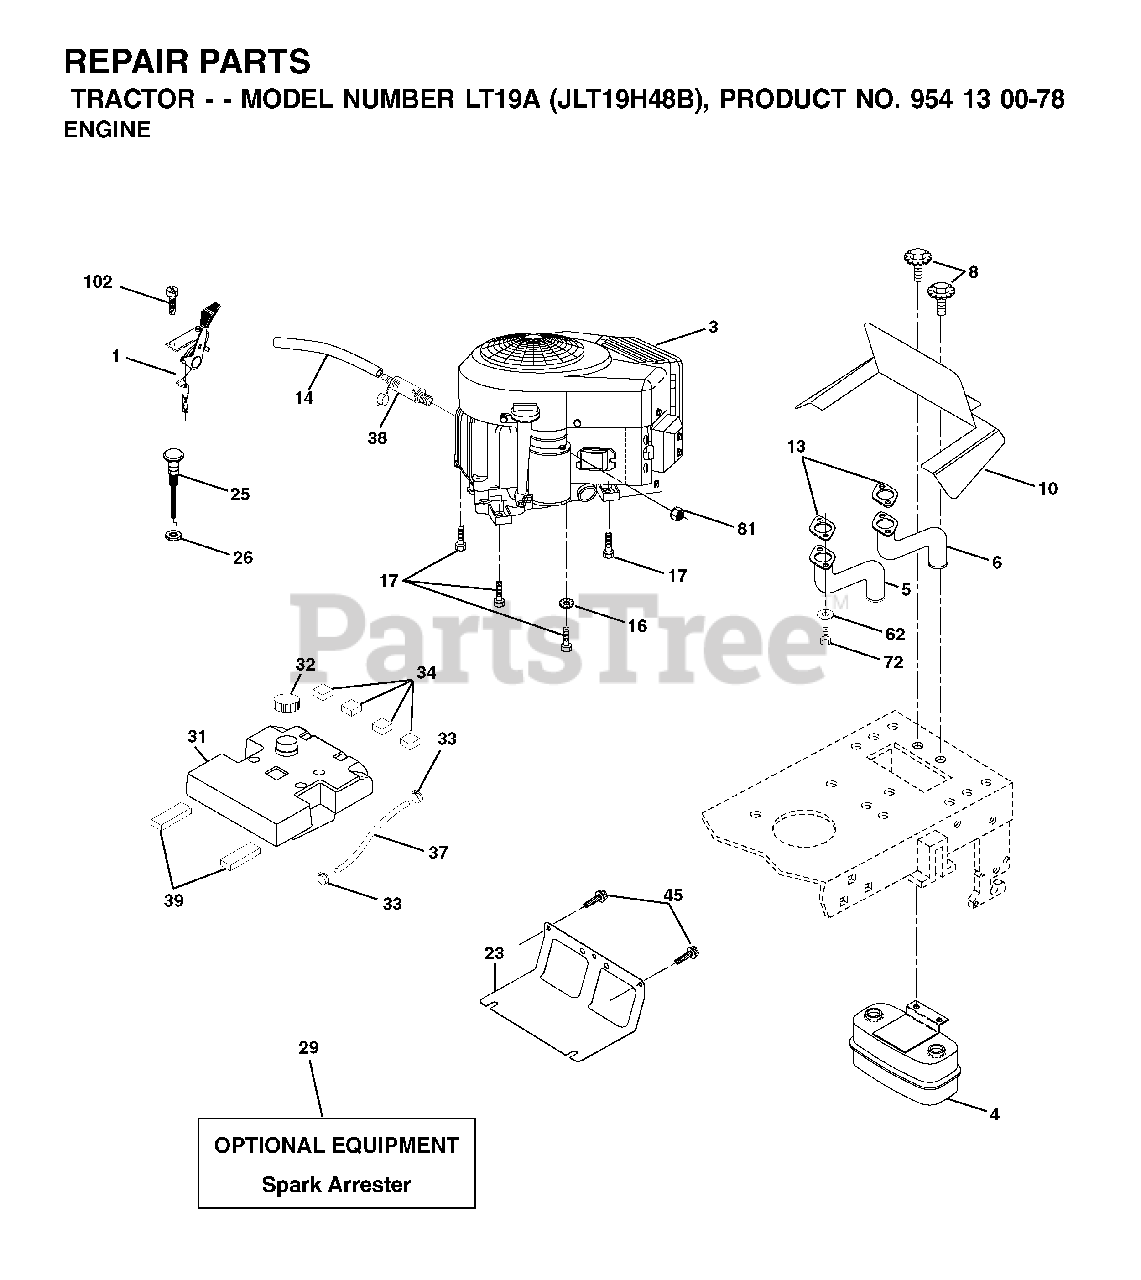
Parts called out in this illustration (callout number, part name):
1	THROTTLE CABLE
4	MUFFLER.TWIN.CYL.LOW.TONE
5	TUBE MANIFOLD LH
6	EXHAUST TUBE RH
8	BOLT, 5/16-18 X 1 3/4
10	SHIELD.BROWNING.B&S
13	GASKET.MUFFLER
14	TUBE, DRAIN OIL ASM.
16	LOCKWASHER
17	SCREW LT
23	SHEILD.BROWNING.DBR.GUARD
25	REPL BY 532 1754-40
26	NUT KEPS 3/8 - 24 UNF
29	ARRESTER SPARK (OPTIONAL)
31	TANK.FUEL(3.5.GAL)
32	FUEL CAP
33	HOSE CLAMP
34	PAD-SPACER LT
38	PLUG, OIL DRAIN EASY
39	PAD IDLER TI
45	SCREW, 3/8-16X3/4
62	LOCKWASHER
72	SCREW
81	NUT
102	SCREW
